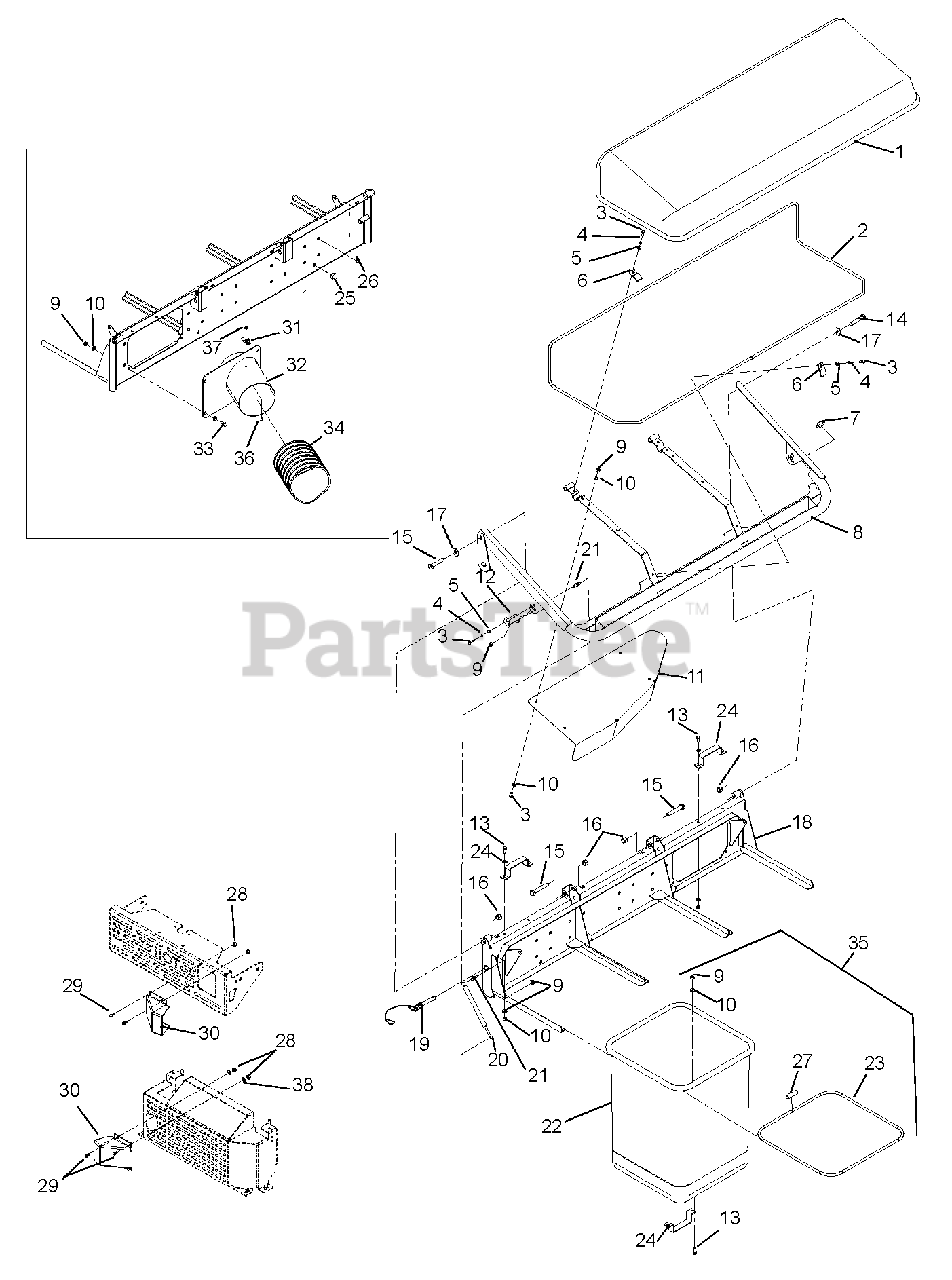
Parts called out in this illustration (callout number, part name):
1	3-Bag Fabric Cover with J-Strip
2	Air Dome Frame .38 Rod
3	Bolt, Hex .25-20 x .75 Grade 5
4	Washer, Locking .25 x .062
5	Washer, Flat Steel .281 x .62 x .065
6	Bracket, Mount Single Hole
7	Hole Plug, Round
8	Cap Support – 3 Bag
9	Nut, .31-18 Nyloc Flange
10	Washer, Flat, Steel .344 x .688 x .065
11	3-Bag Deflector
12	Bracket, Gas Cylinder Mount
13	Bolt, Hex .31-18 x .75 Grade 5
14	Bolt, Hex .50-13 x 2.50 Grade 5
15	Bolt, Hex .50-13 x 3.00 Grade 5
16	Nut, Locking Nylon .50-13
17	Washer, Flat Steel .531 x 1.06 x .095 YWZC
18	3-Bag Support Mount
19	Detent Pin with Lanyard 1/2 x 2-.50
20	Gas Cylinder
21	Ball Stud
22	Cloth Bag
23	Grass Bag Frame
24	Bag Handle
25	Rubber Bumper
26	Hole Plug 7/16
27	Tube Connector
28	Nut, Locking Center .25-20 (200 Series Vertical Shaft)
29	Bolt, Hex .25-20 x .50 Grade 5 (200 Series Vertical Shaft)
30	Deflector, Exhaust
31	Thumb Latch, A-10 Quick Release
32	Inlet Adapter 200 Series
33	Bolt, Hex .31-18 x 1.00 Grade 5
34	Hose, Bagger – 49"
35	Bag Assembly
36	Screw, Machine 10-24 x .50 Hex Washer Head
37	Nut, Locking Nylon 10-24 with Insert
38	Washer, Flat Steel .312 x .734 x .065
